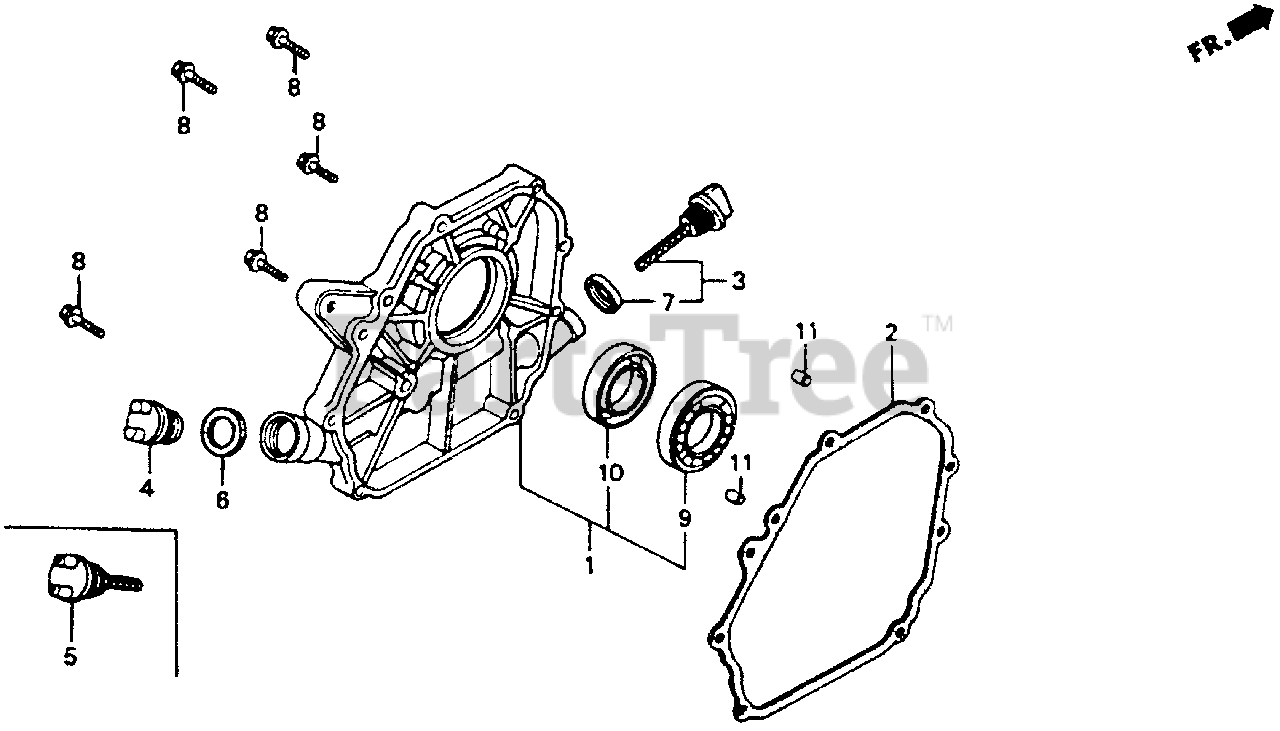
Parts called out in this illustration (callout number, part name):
1	COVER ASSY., CRANKCASE
2	GASKET, CASE COVER
2	GASKET, CASE COVER (NON-ASBESTOS)
3	CAP ASSY., OIL FILLER (GRAY)
4	CAP, OIL FILLER
5	CAP, OIL HOLE
6	GASKET, OIL FILLER CAP
7	GASKET, OIL FILLER CAP
8	BOLT, FLANGE (8X32)
9	BEARING, RADIAL BALL (6205)
10	OIL SEAL (25X41X6)
11	PIN, DOWEL (8X14)
